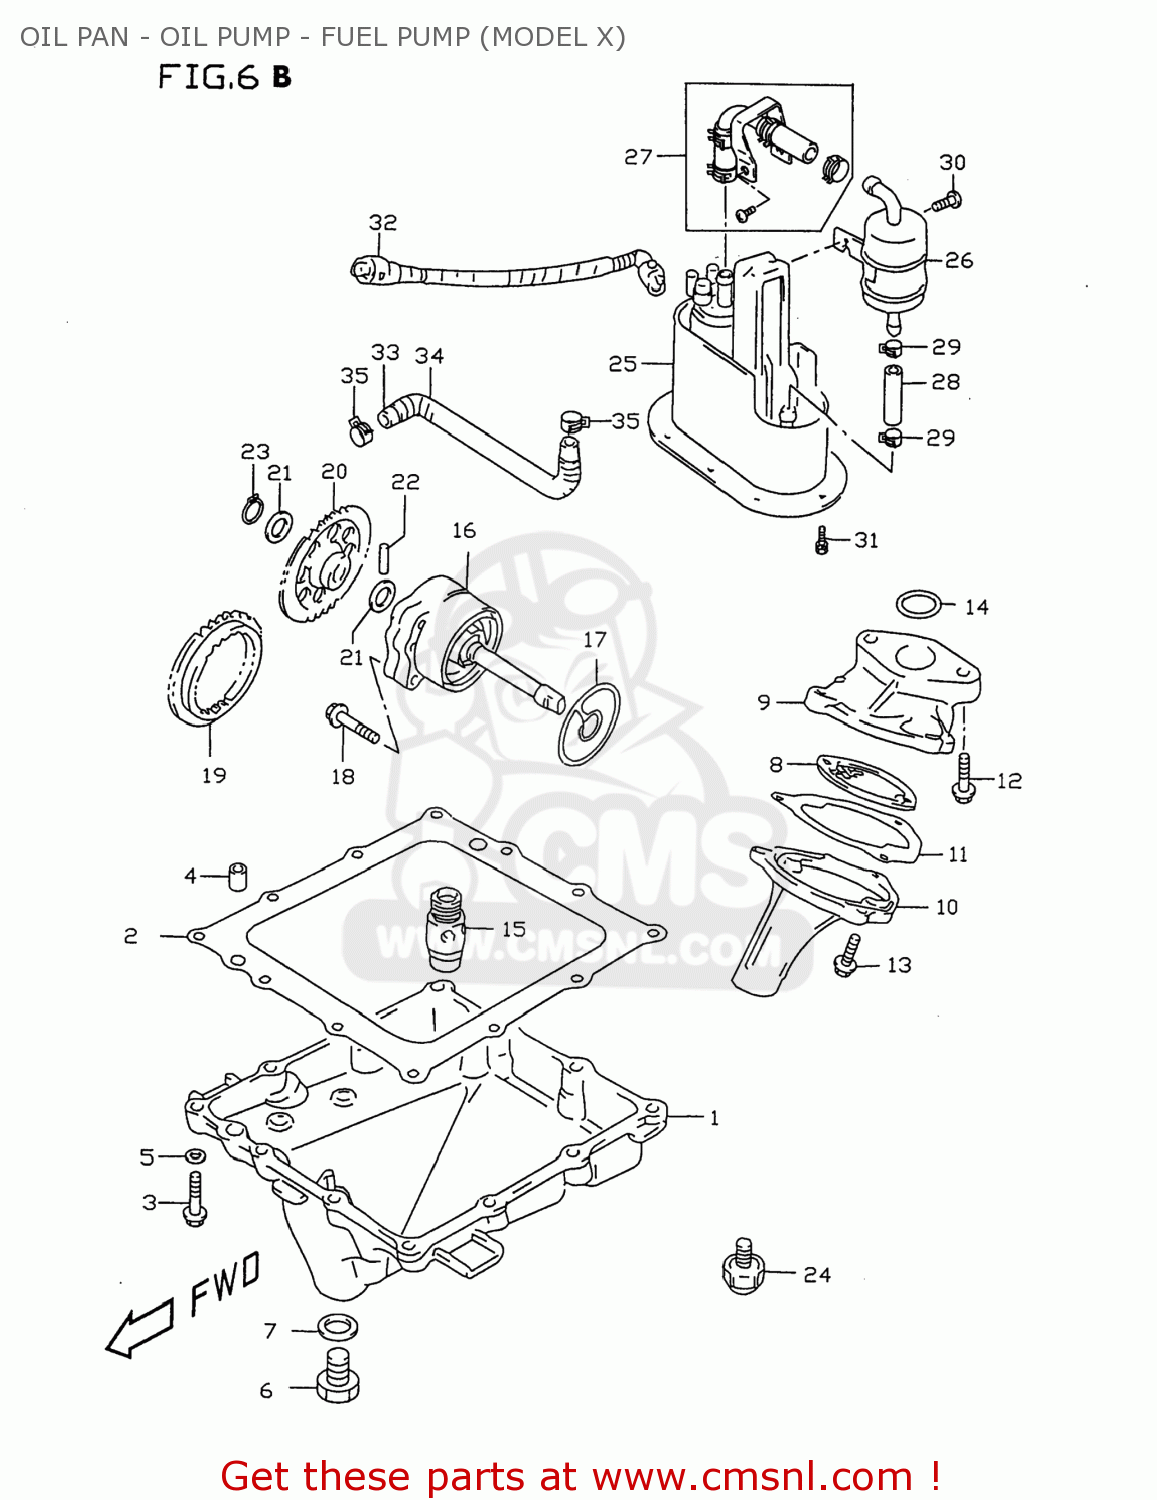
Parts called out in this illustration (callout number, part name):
1	PAN,OIL
2	GASKET,OIL PAN (NAS)
3	BOLT,G/S SWITC
4	PIN
5	GASKET(5.8X11X1.2) (NAS)
6	PLUG
7	GASKET(13.8X18.8X4.8) (NAS)
8	STRAINER,ENGINE OIL
9	PROTECTOR,OIL STRAINER
10	COVER,OIL STRAINER
11	GASKET,OIL STRAINER
12	BOLT
13	BOLT
14	O RING(D:2.62,ID:20.3)
15	VALVE ASSY,OIL RELIEF
16	PUMP ASSY,ENGINE OIL
17	O RING,OIL PUMP
18	BOLT
19	GEAR,OIL PUMP DRIVE
20	GEAR,OIL PUMP DRIVEN
21	SHIM(12X20X0.5)
22	PIN(5X18)
23	CIRCLIP,12 MM
24	SWITCH ASSEMBLY,OIL PRESSURE
25	PUMP ASSEMBLY,FUEL
26	FILTER,FUEL
27	HOSE SET
28	HOSE(7.6X14X600)
29	CLIP
30	SCREW
31	BOLT,FUEL PUMP
32	HOSE,FUEL
33	HOSE(5.4X11.4X600)
34	(CA) SPRING
35	CLIP
